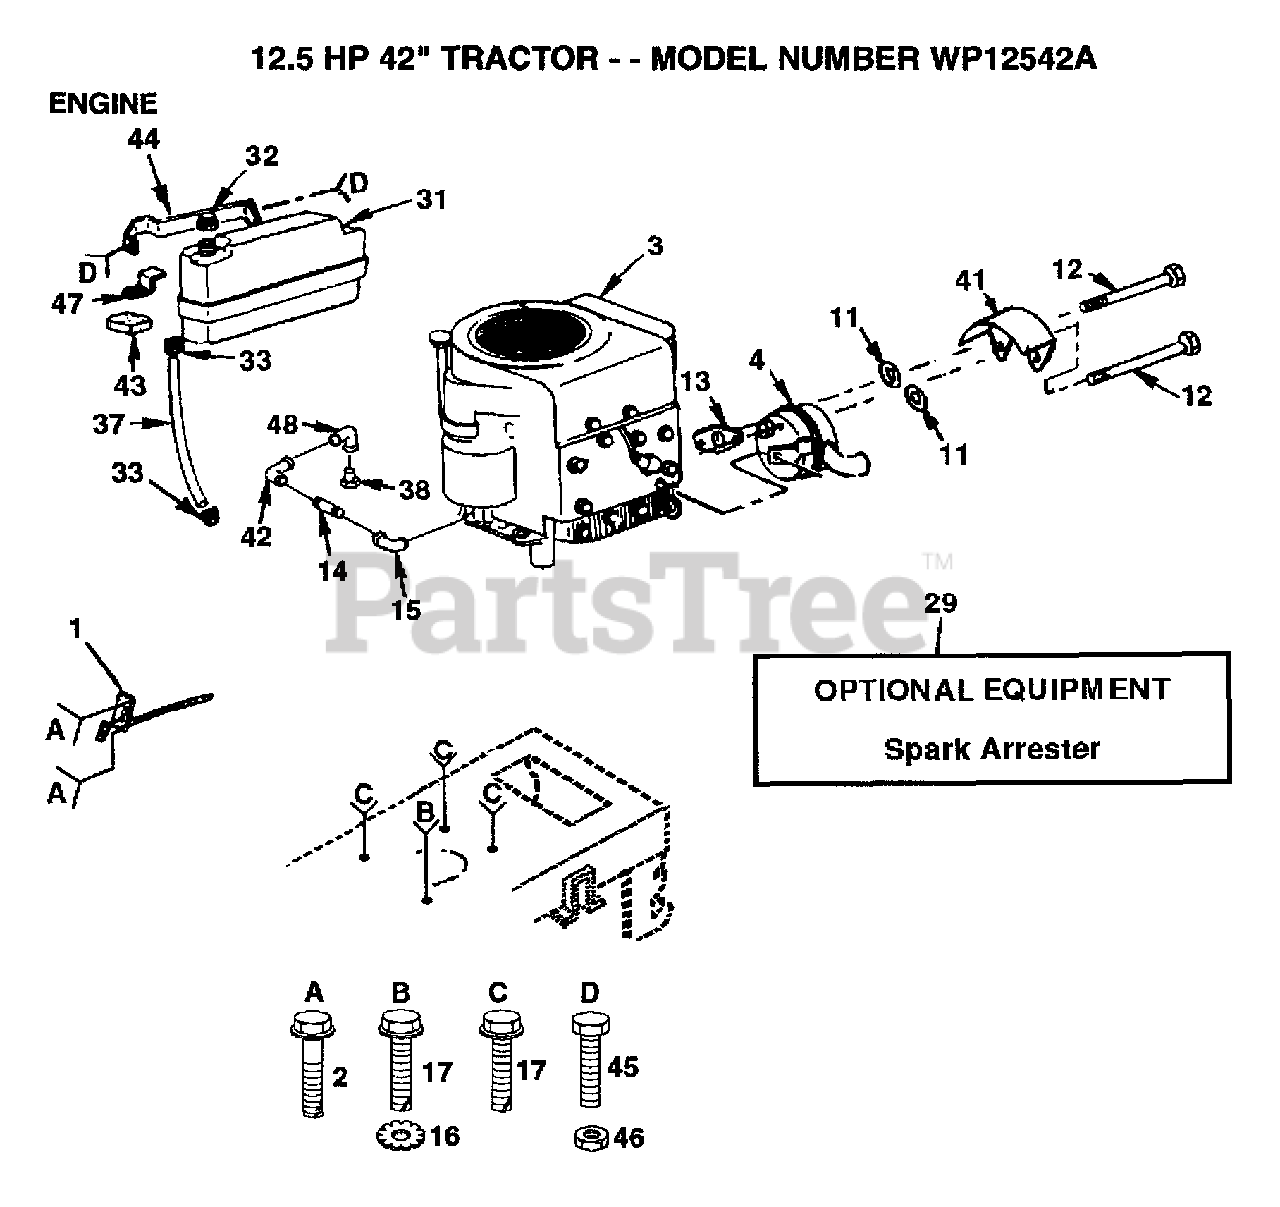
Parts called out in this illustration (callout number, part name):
1	THROTTLE CONTROL
2	SCREW LT
4	MUFFLER
12	BOLT
14	PIPE NIPPLE
15	STREET ELBOW LT
16	LOCKWASHER
17	SCREW
31	FUEL TANK
33	HOSE CLAMP
37	HOSE T
41	HEAT SHIELD
42	STREET ELBOW LT
43	PAD-SPACER T
44	SUPT TANK FUEL
45	BOLT
47	BRACE-TANK LT
48	ELBOW
